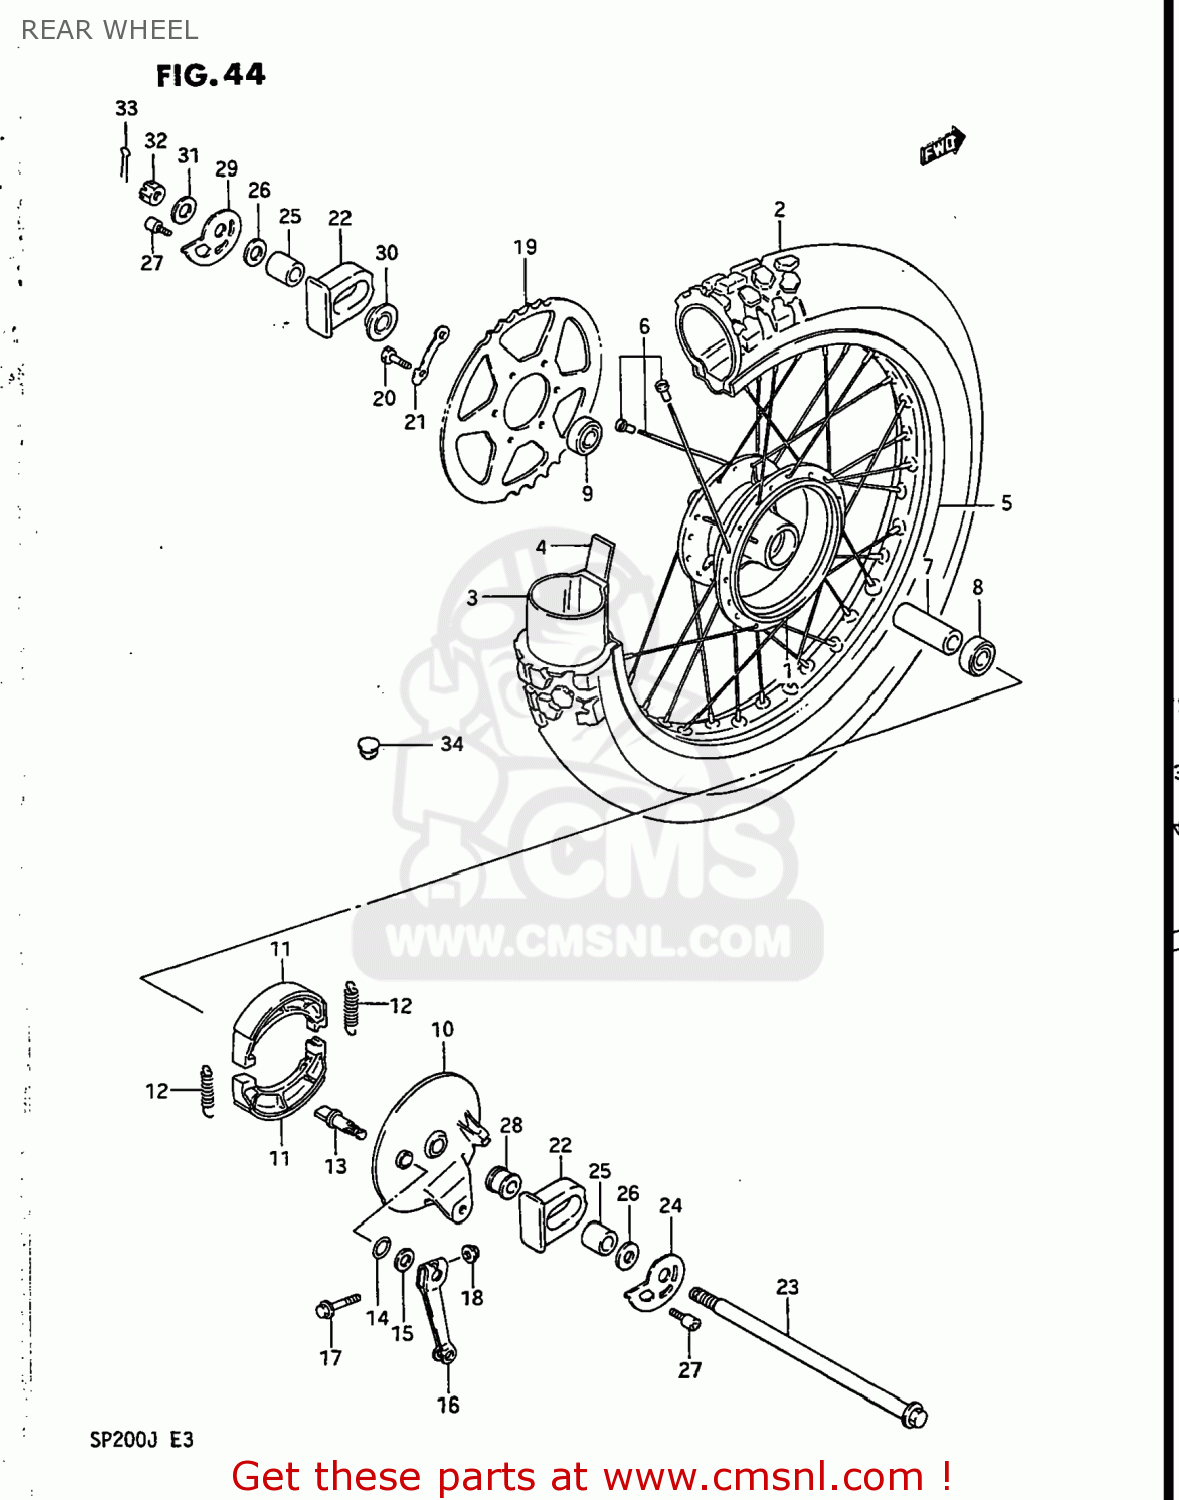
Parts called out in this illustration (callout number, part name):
1	HUB,REAR
2	TIRE
3	TUBE ASSEMBLY,WHEEL,INNER
4	PROTECTOR,WHEEL,INNER
5	RIM,REAR WHEEL
6	SPOKE SET,RR WHEEL
7	SPACER(15.3X21.7X107.5)
8	BEARING
9	BEARING
10	PANEL,RR BRAKE ANCHOR
11	SHOE,BRAKE
12	SPRING(L:34)
13	CAM,FRONT BRAKE
14	O-RING (D:2.4 ID:13.8)
15	WASHER (14.5X22X1.6)
16	LEVER,RR BRAKE CAM
17	BOLT
18	NUT
19	SPROCKET,REAR
20	BOLT(8X30)
21	WASHER
22	CAP,RR SWINGING ARM
23	AXLE,REAR
24	ADJUSTER,CHAIN,R
25	SPACER,CHAIN ADJUSTER
26	WASHER(15.5X30X3.2)
27	BOLT,CHAIN ADJUSTER
28	SPACER,RR AXLE,R
29	ADJUSTER,CHAIN,L
30	SPACER,RR AXLE,L
31	WASHER
32	NUT 14MM
33	COTTER PIN
34	CAP(OD:12)
